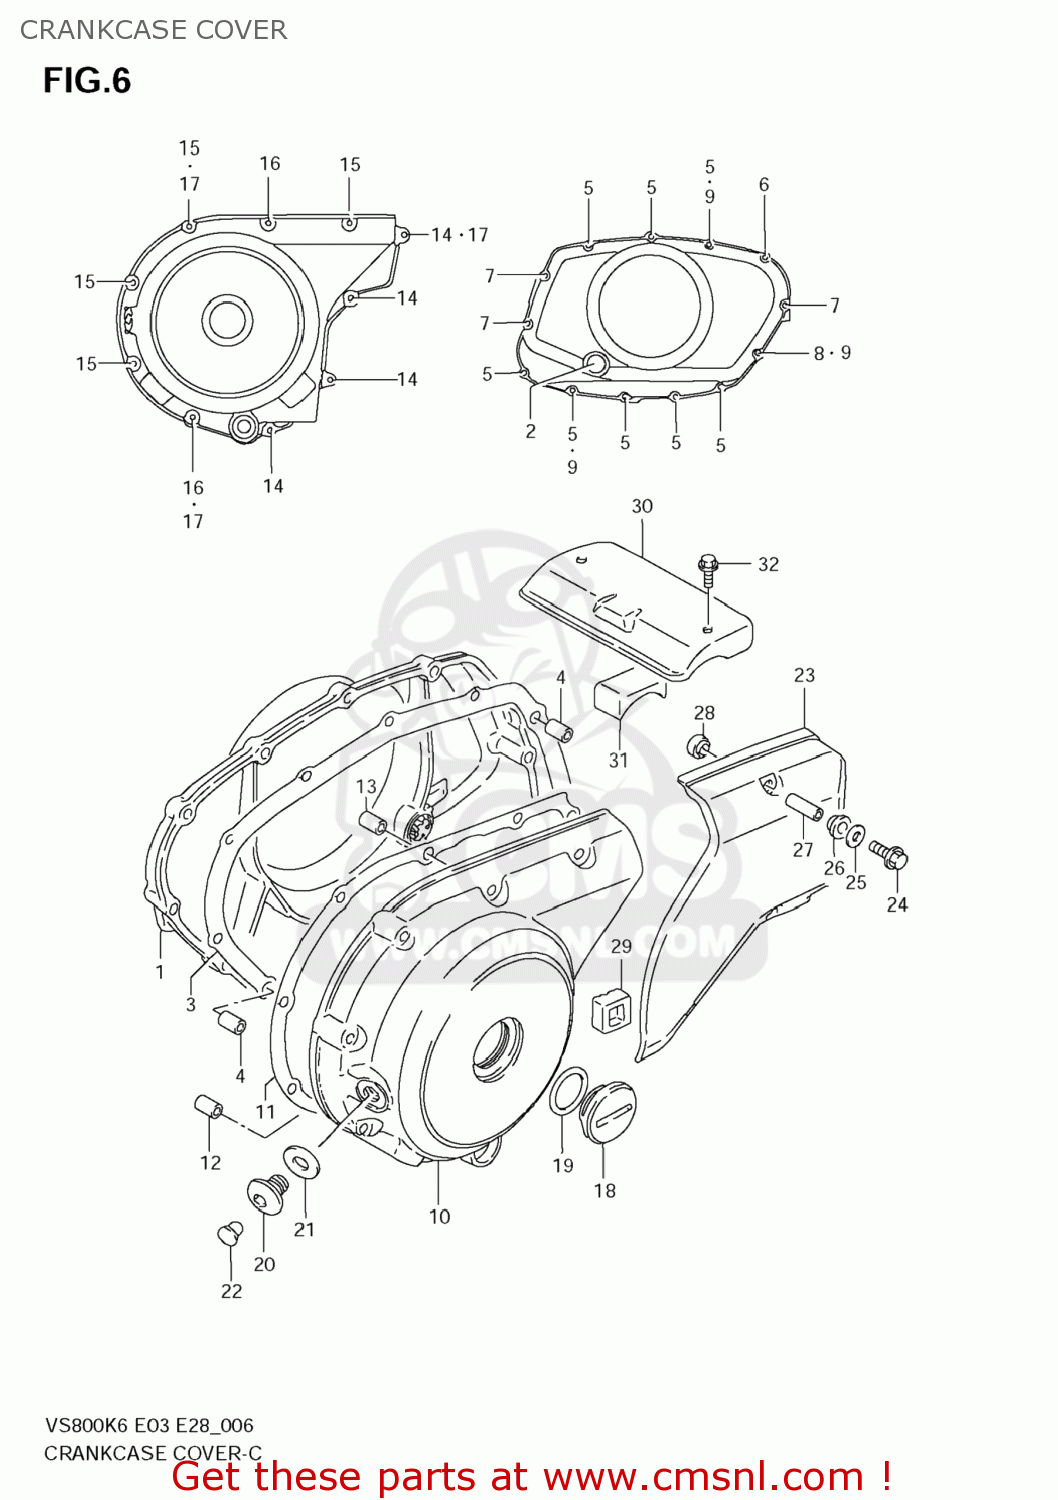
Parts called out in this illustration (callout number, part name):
1	COVER,CLUTCH
2	LENS,OIL LEVEL CHECK
3	GASKET,CLUTCH COVER (NAS)
4	PIN
5	BOLT(6X30)
6	BOLT(6X35)
7	BOLT(6X45)
8	BOLT(6X60)
9	GASKET(5.8X13X1.2) (NAS)
10	COVER,GENERATOR
11	GASKET,GENERATOR COVER (NAS)
12	PIN(8.4X11X20)
13	PIN
14	BOLT(6X30)
15	BOLT(6X40)
16	BOLT(6X50)
17	GASKET(5.8X13X1.2) (NAS)
18	Chrome Crankshaft Plug
19	O RING(D:3.1,ID:32.7)
20	PLUG,14X12
21	GASKET(13.8X18.8X4.8) (NAS)
22	CAP(OD:12)
23	COVER,SECONDARY GEAR CASE
24	BOLT(6X45)
25	WASHER(6.5X14X1.6)
26	WASHER(8.7X15X2.1)
27	SPACER(6.5X9X33.3)
28	WASHER(8.7X16X5)
29	DAMPER,SECONDARY COVER
30	COVER,STARTER MOTOR
31	DAMPER,MOTOR COVER
32	BOLT
